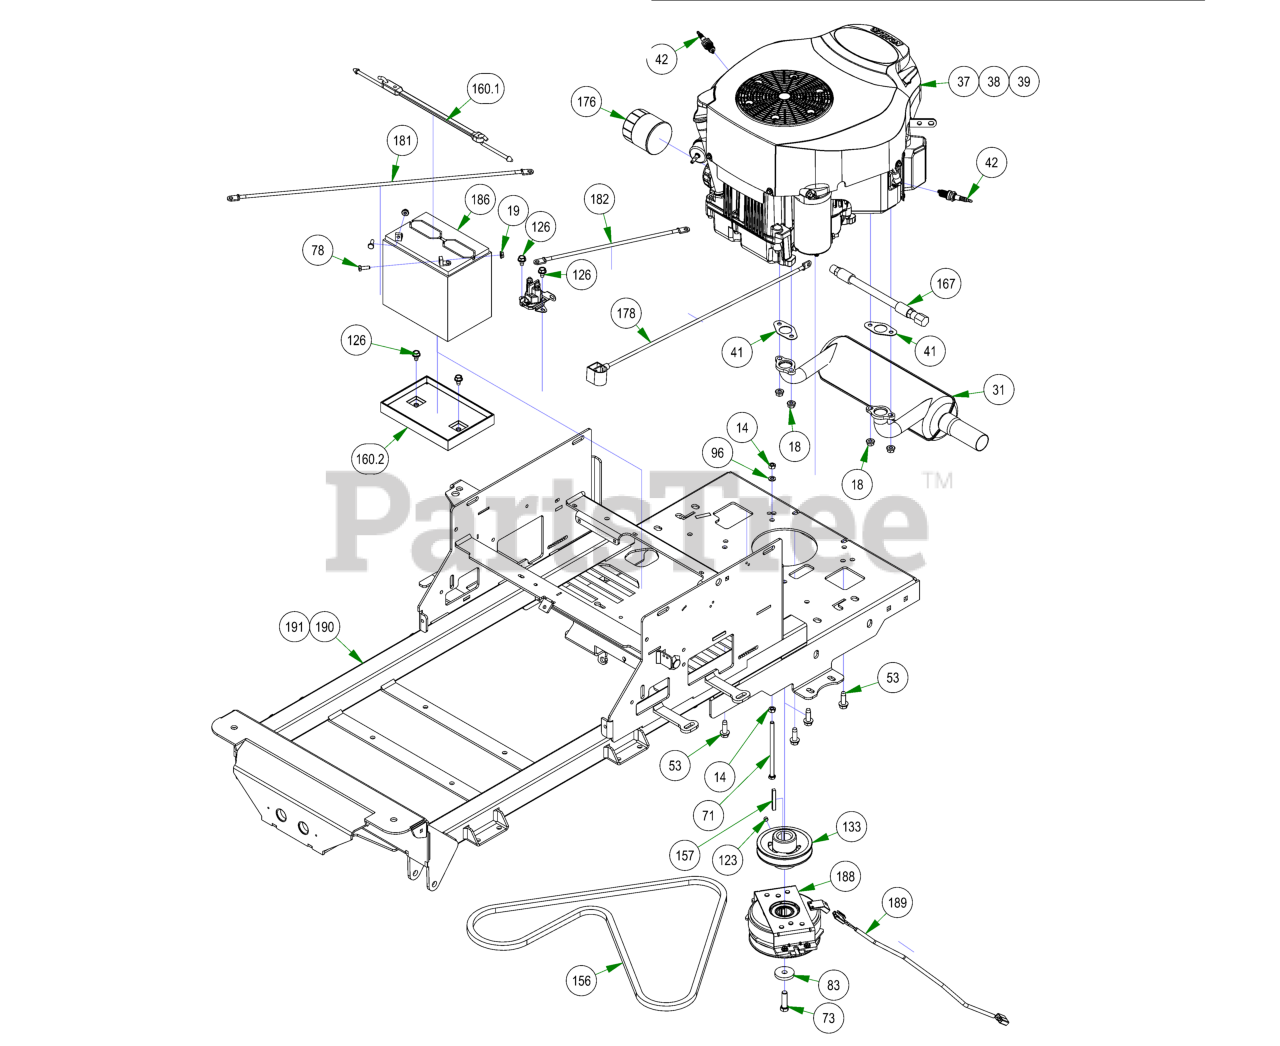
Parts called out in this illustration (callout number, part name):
14	5/16-18 HEX NUT ZINC
18	M8 Nut Connects the 015-1012-00 and the 015-8240-00
19	1/4-20 HEX SERRATED FLANGE NUT HARD/ZINC
31	Kohler Muffler
37	Kohler-2014 ZT 725cc
38	26hp Kohler-2018 ZT-KT745-3088
39	Kohler-2014 CZT/Outlaw 747cc
41	Exhaust Gasket
42	Spark Plug
53	3/8-16 X 1-1/8 HEX WASHER UNSLOT SERRATED (TRI-LOB) TRS ZINC YELLOW
71	5/16-18 X 5-1/2 HEX CAP SCREW (GR.5) ZINC
73	7/16-20 X 1-1/2 HEX CAP SCREW (GR.8) w/ Patch
78	1/4-20 X 3/4 HEX CAP SCREW (GR.5) ZINC
83	CLUTCH WASHER
96	5/16 SPLIT LOCKWASHER ZINC
123	5/16-24 X 1/4 SOCKET SET SCREW (CUP PT) PLAIN
126	5/16-18 X 1/2 HWH unslot (F) tcs zinc
133	4 3/4 Motor Pulley
157	1/4 X 2 SQ MACHINERY KEY 1018 STL PLAIN
160	2023 Battery Hold Down Assembly Strap
160.1	2023 Rubber Battery Hold Down Strap
160.2	Battery Tray
167	Oil drain Hose
176	25 HP Kohler Oil Filter ZT?MZ
177	Universal Inline Fuel Filter
178	24 inch Black Cable – MZ/ZT
181	24" Red Battery Cable
182	12 in red battery cable
186	SP-35 Battery
189	Clutch Pigtail
190	2023 ZT Elite Frame- Painted
191	2023 ZT Elite Frame- Painted
